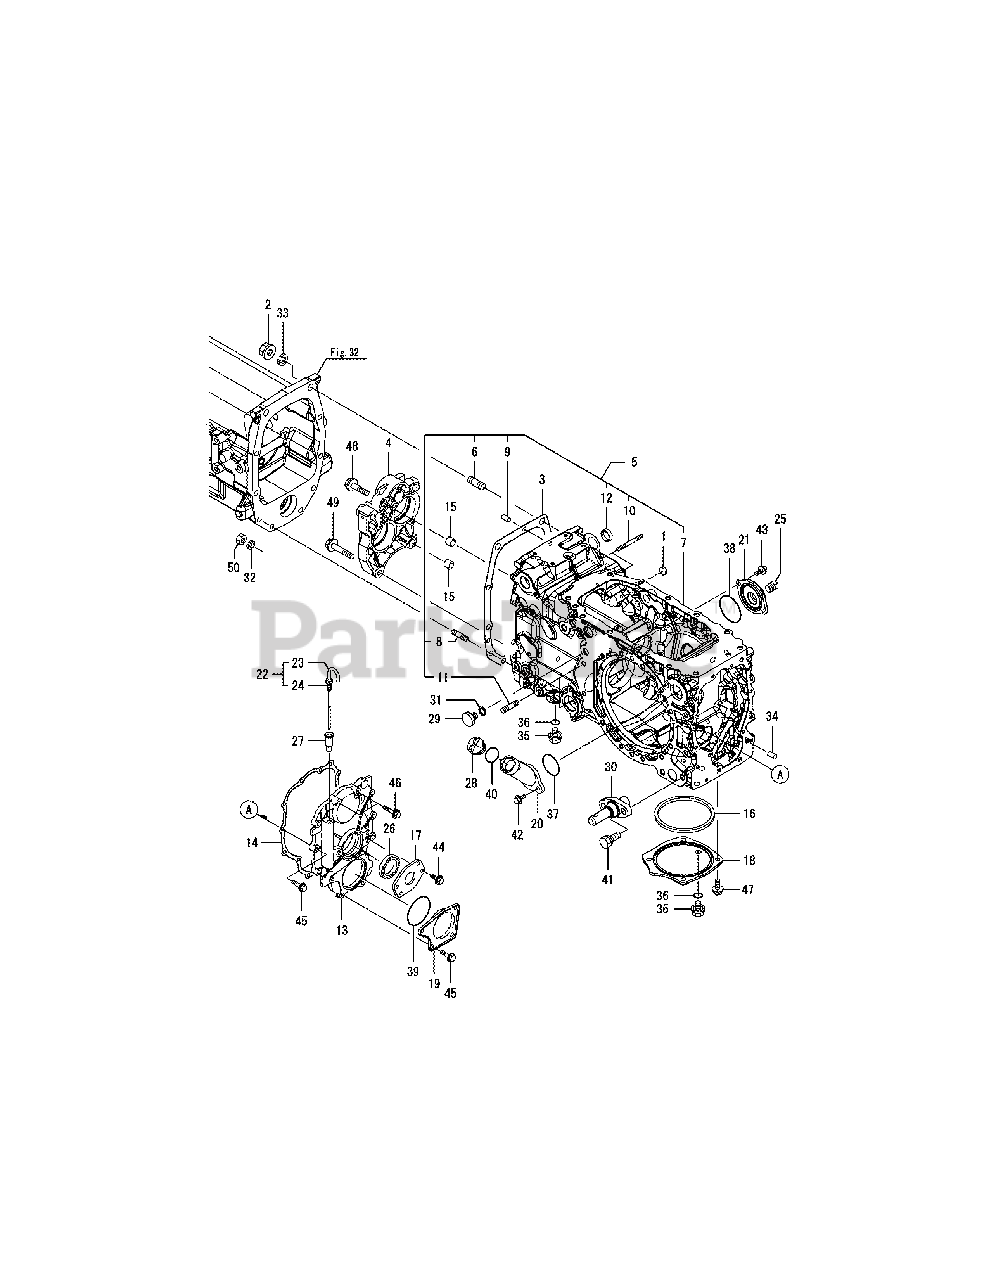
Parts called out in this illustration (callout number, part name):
3	GASKET, TRANS.
4	RETAINER, BEARING
5	HOUSING ASSY, TRANS.
7	HOUSING,TRANSMISSION
9	PARALLEL PIN 10X 18
10	STUD M 8X 80 PLATED
11	STUD,BOLT 12 X 50
14	GASKET, REAR COVER
15	COLLAR 13X17X14
16	COUPLING 140=3
17	PLATE, OIL SEAL
19	COVER, REAR COVER
21	COVER, STRAINER
22	GAUGE ASSY, OIL
26	SEAL TC 426009, OIL
27	GUIDE, DIPSTICK
30	PIN, LOWER LINK
32	SPRING WASHER 12
33	SPRING WASHER 16
34	PARALLEL PIN 10X 18
36	O-RING 1A P-16.0
37	O-RING 1A P-50.0
38	O-RING 1A G-65.0
39	O-RING 1A G-75.0
40	O-RING 1A 2030
41	BOLT W/WASHER M14X35
42	BOLT M 8X 16 PLATED
43	BOLT M 8X 20 PLATED
44	BOLT M 8X 20 PLATED
45	BOLT M 8X 30 PLATED
46	BOLT M 8X 40 PLATED
47	BOLT M10X 25 PLATED
